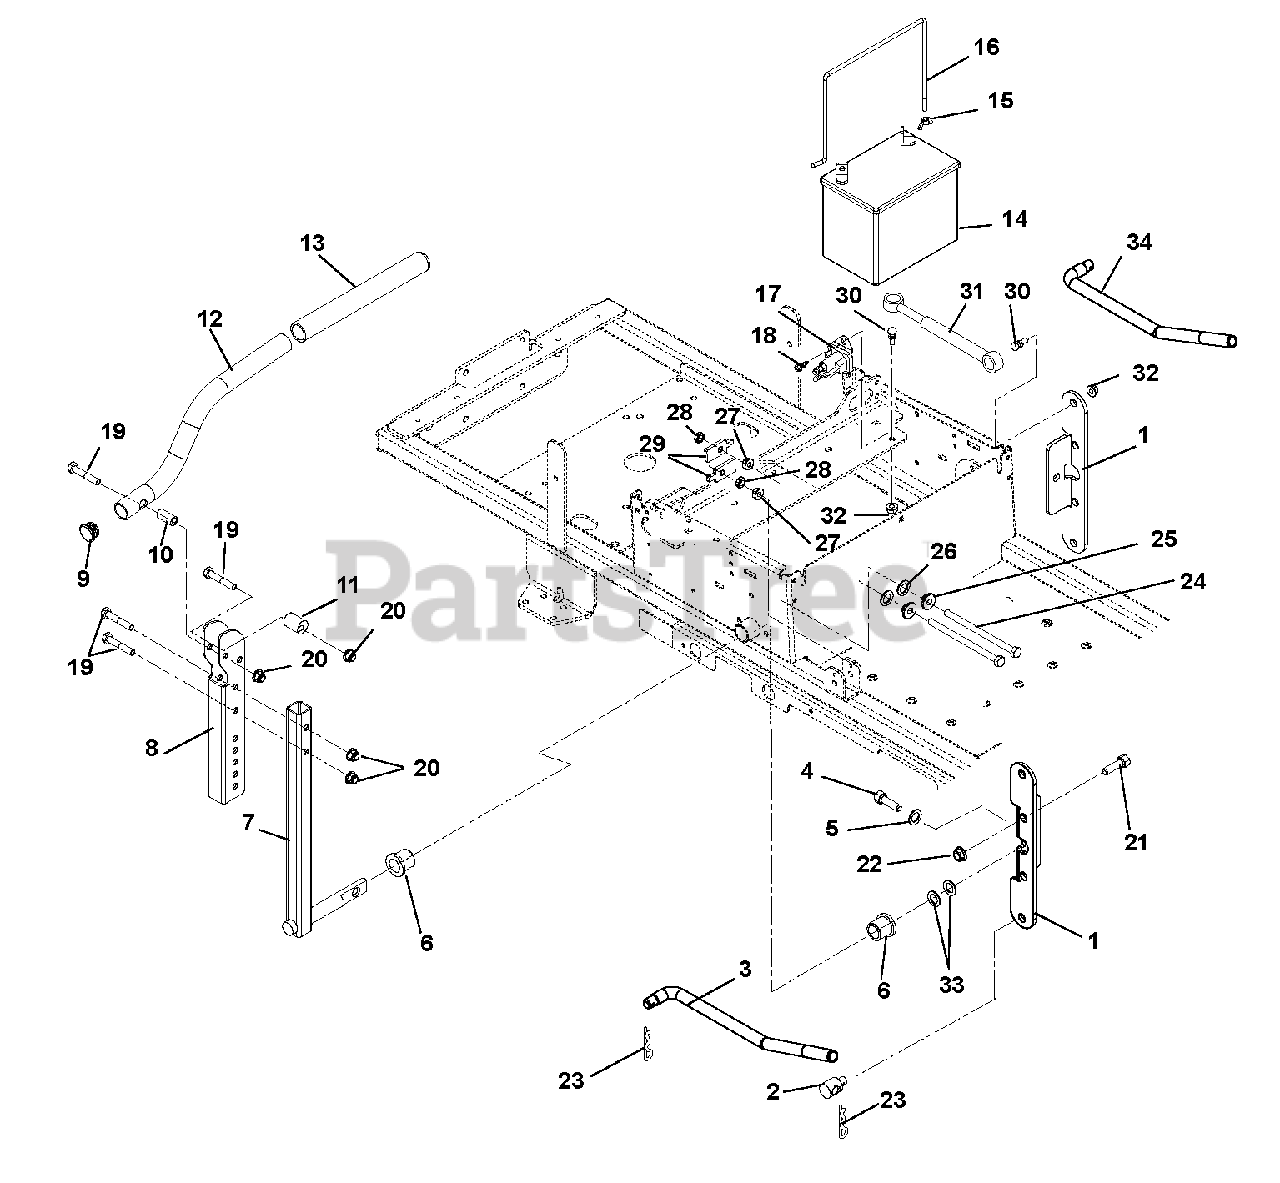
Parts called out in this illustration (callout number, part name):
1	Weldment, Control Link
2	Pivot, Rod
3	Link, Wireform Left Hand
4	Bolt, .38-16 x 1 Grade 8 EP30
5	Washer, Flat Steel .390 x 1.5 x .125
6	Bushing, 1.00 x .75 x 1.00
7	Weldment, Control Arm
8	Channel, Upper Handlebar
9	Caplug, Handlebar
11	Eccentric
12	Handlebar
13	Grip, Handlebar
15	Nut, Lock Wing .250-20
16	Battery Rod
17	Solenoid
18	Screw, Tap .250-20 x .37
19	Bolt, Hex .31-18 x 1.75 Grade 5
20	Nut, 5/16-18 Flange Nyloc
21	Bolt, Hex .38-16 x 1.25 Grade 5
22	Nut, Hex Jam .375-16
23	Pin, Hair Internal .08 x .18 x 1.18
24	Bolt, Hex 5/16-18 x 5 Grade 2
25	Bushing, Flange .312 x .500 x .344 x .880
26	Washer, Flat Steel .52 x .827 x .062
27	Nut, Spin Lock, Flange .312-18
28	Nut, Jam .312-18
29	Stop Tab
30	Stud, Ball
31	Damper, Control
32	Nut, Locking Top Flange .31-18
33	Washer, Flat Steel .755 x 1.25 x .125
34	Link, Wireform Right Hand
